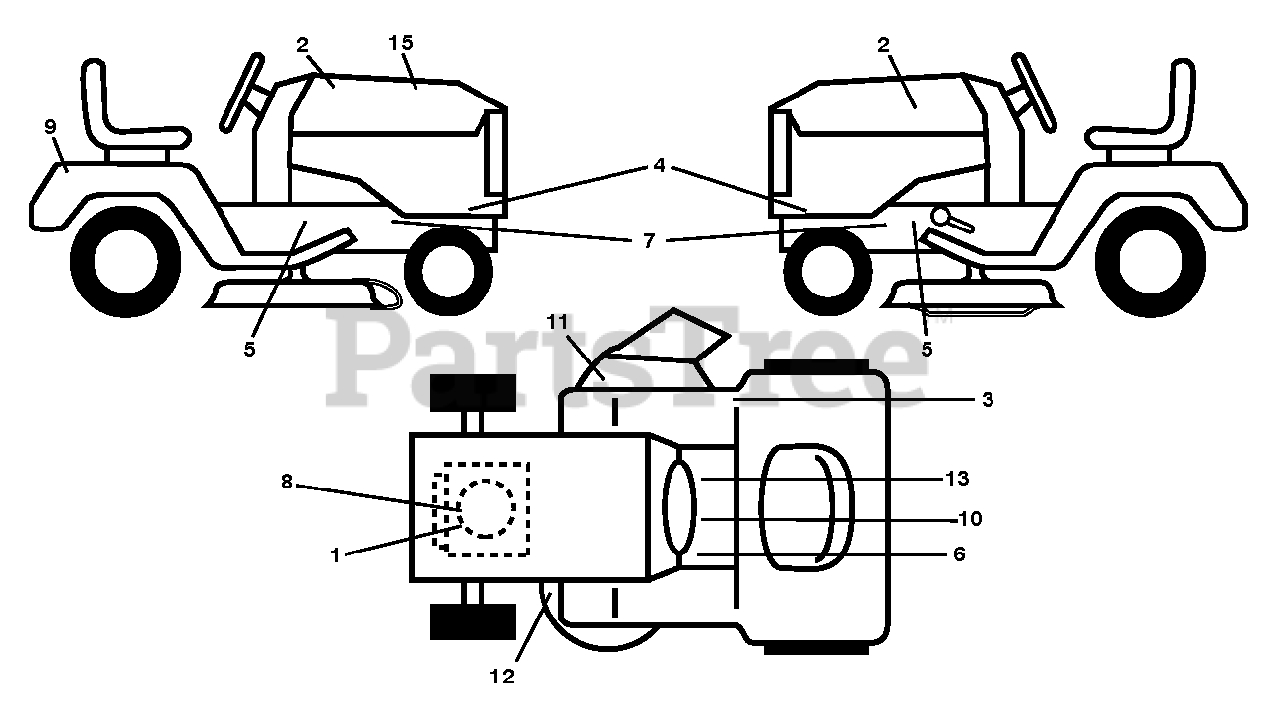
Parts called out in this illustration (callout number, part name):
1	DECAL
2	RP.DECAL.BADGE.170MM.TEXTLOGO
3	Decal, Fender 100 DB/CE
6	DECAL
8	DECAL
9	DECAL BTRY SYMBOLS
10	LABEL
11	DECAL.WARN.DFLECT/CTFINGR.SRD
12	Decal, Mower V-Belt Schematic
13	DECAL PARK BRAKE
15	DECAL DECAL.RPL.BSM21.PB.SRD.3
